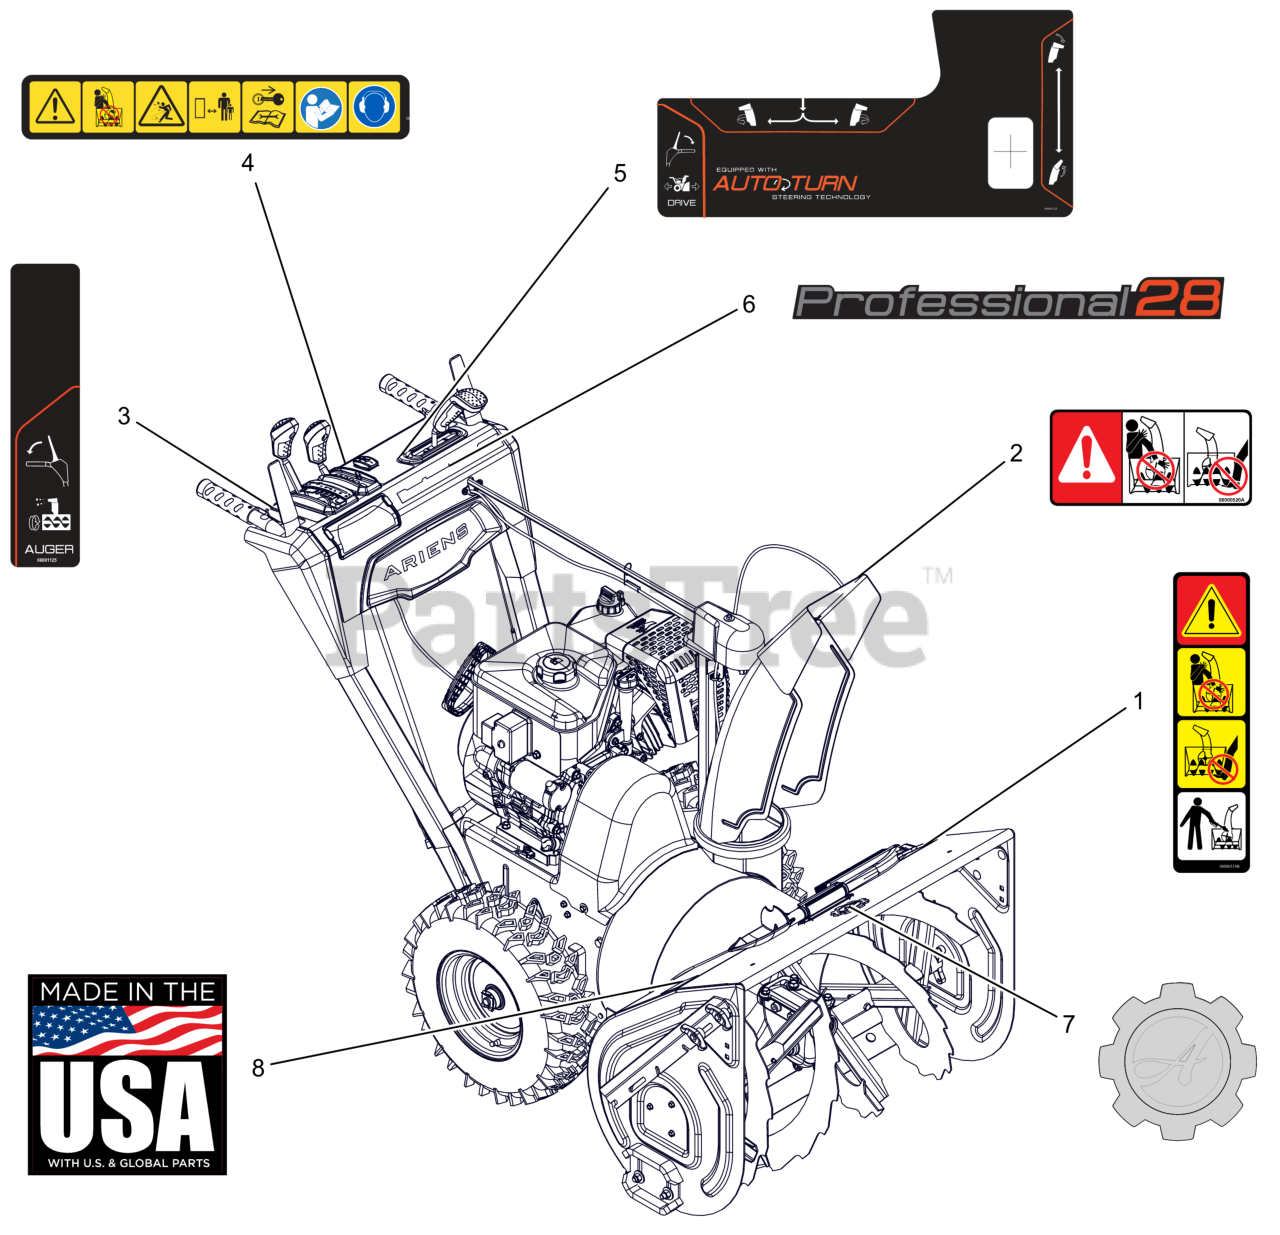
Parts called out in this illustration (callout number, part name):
1	DECAL, DANGER - ROTATING PARTS
2	DECAL, DANGER
3	DECAL,CONTROL-RH CONTROL
4	DECAL,DASH - SAFETY
5	DECAL,CONTROL-LG QT2
6	DECAL, DASH - PRO 28
7	DECAL, ARIENS-GEAR BADGE -THK
8	DECAL, MADE IN USA
